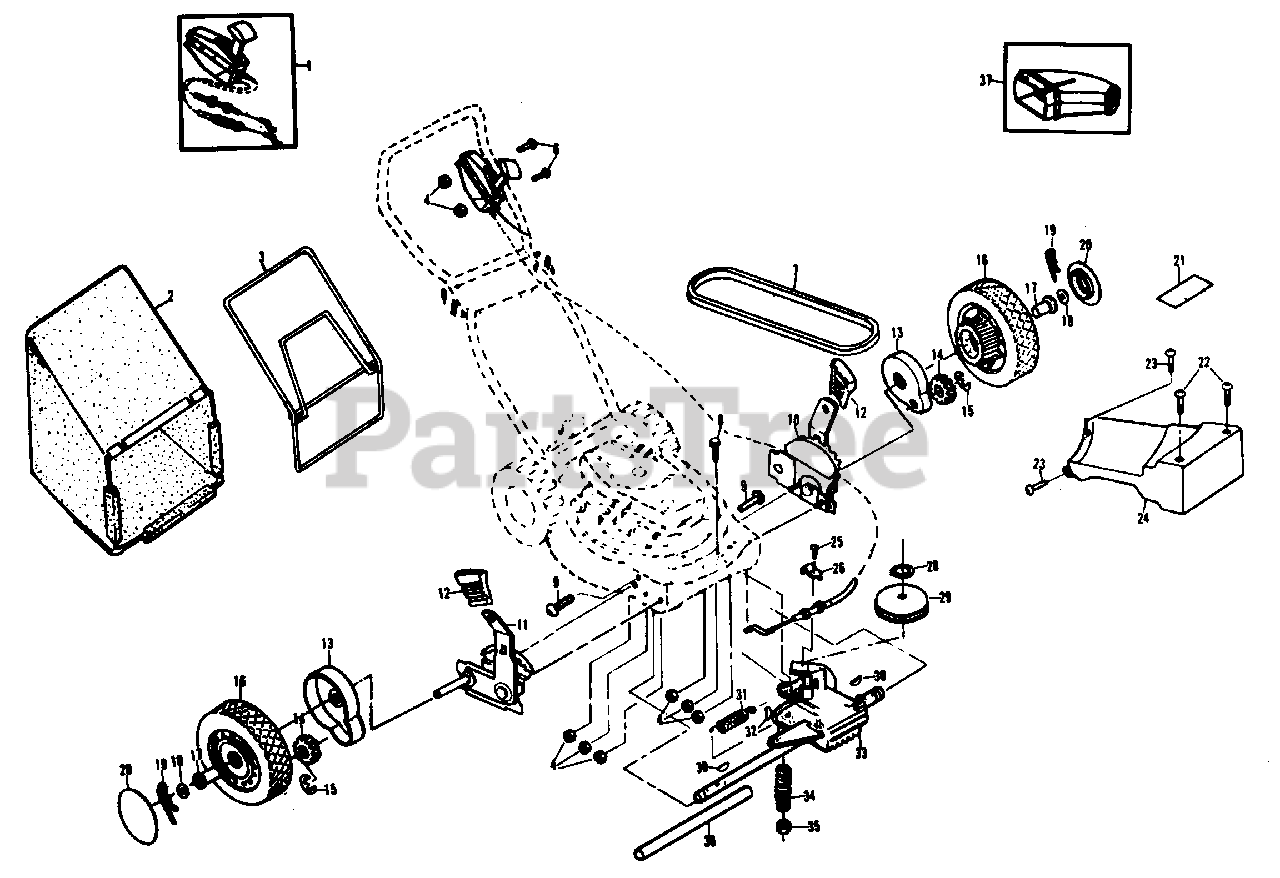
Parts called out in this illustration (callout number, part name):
1	Dual Head Drive Control (Complete)
2	Grass Bag Assembly
3	Catcher Frame (AYP part number)
4	Locknut (AYP part number)
6	Machine Screw (AYP part number)
7	V-Belt (AYP part number)
8	Hex Head Bolt (AYP part number)
9	Flat Head Machine Screw (AYP part number)
10	Wheel Adjuster Assembly (Left)
11	Wheel Adjuster Assembly (Right)
12	Selector Knob (AYP part number)
13	Dust Cover (AYP part number)
14	Pinion (AYP part number)
15	E-Ring (AYP part number)
16	Wheel & Tire Assembly (AYP part number)
17	Wheel Bushing (AYP part number)
18	Flat Washer (AYP part number)
19	Retainer Clip (AYP part number)
21	Drive Cover Deal (AYP part number)
22	Pan Head Tapping Screw (AYP part number)
23	Hex Washer Head Screw (AYP part number)
24	Drive Cover (AYP part number)
25	Hex Washer Head Tapping Screw (AYP part number)
26	Cable Clamp (AYP part number)
28	Retaining Ring (AYP part number)
29	Drive Pulley (AYP part number)
30	Woodruff Key #3 (AYP part number)
32	Woodruff Key #213 (AYP part number)
33	Gear Case Assembly Kit (AYP part number)
34	Spring (AYP part number)
35	Locknut (AYP part number)
36	Drive Shaft Cover (AYP part number)
